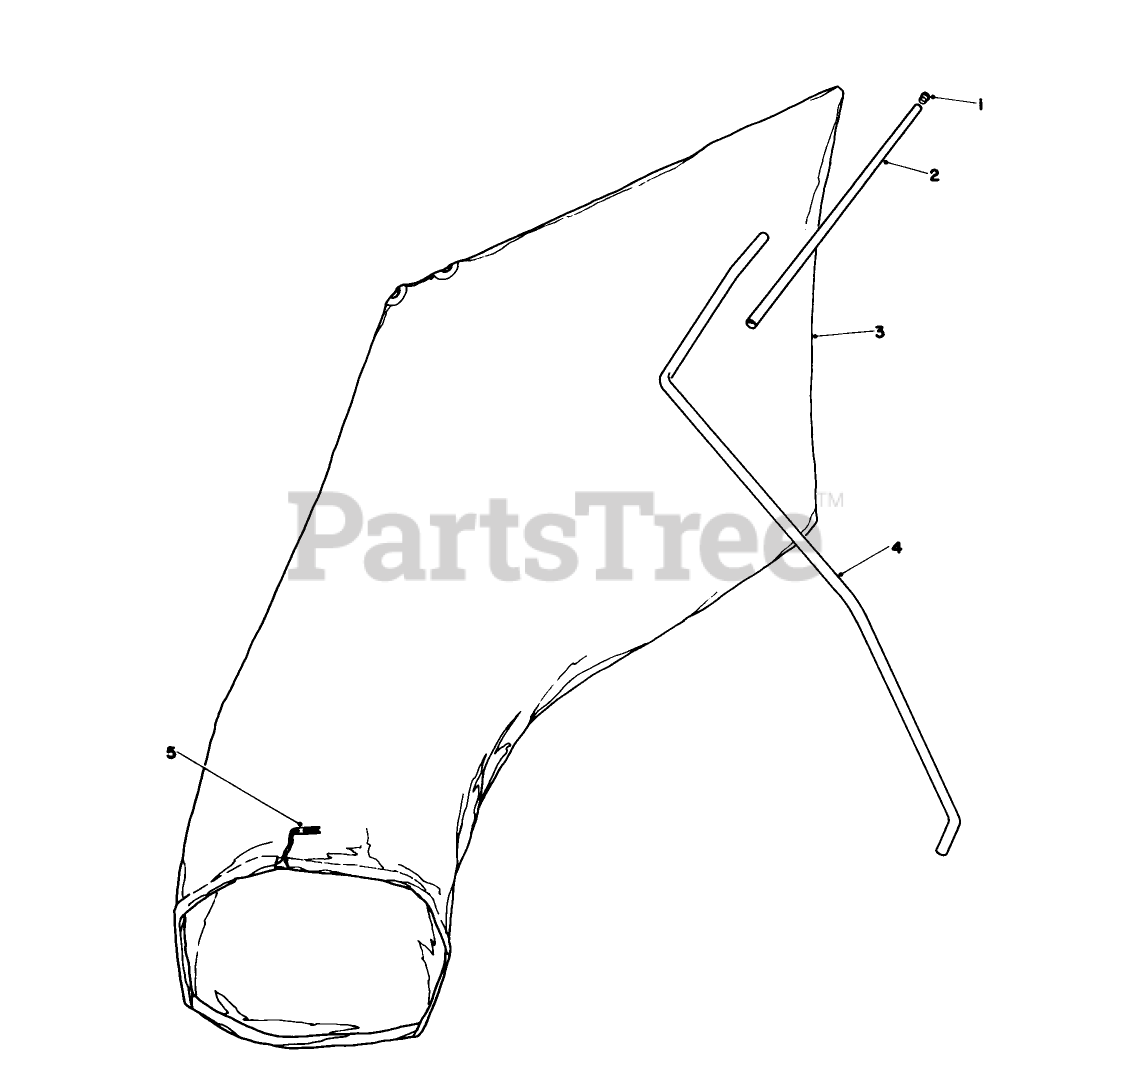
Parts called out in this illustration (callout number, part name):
2	BAG HANGER TUBE
3	Bag (Incl. Ref. #5)
4	HANGER ROD
5	BAG CORD FASTENER
